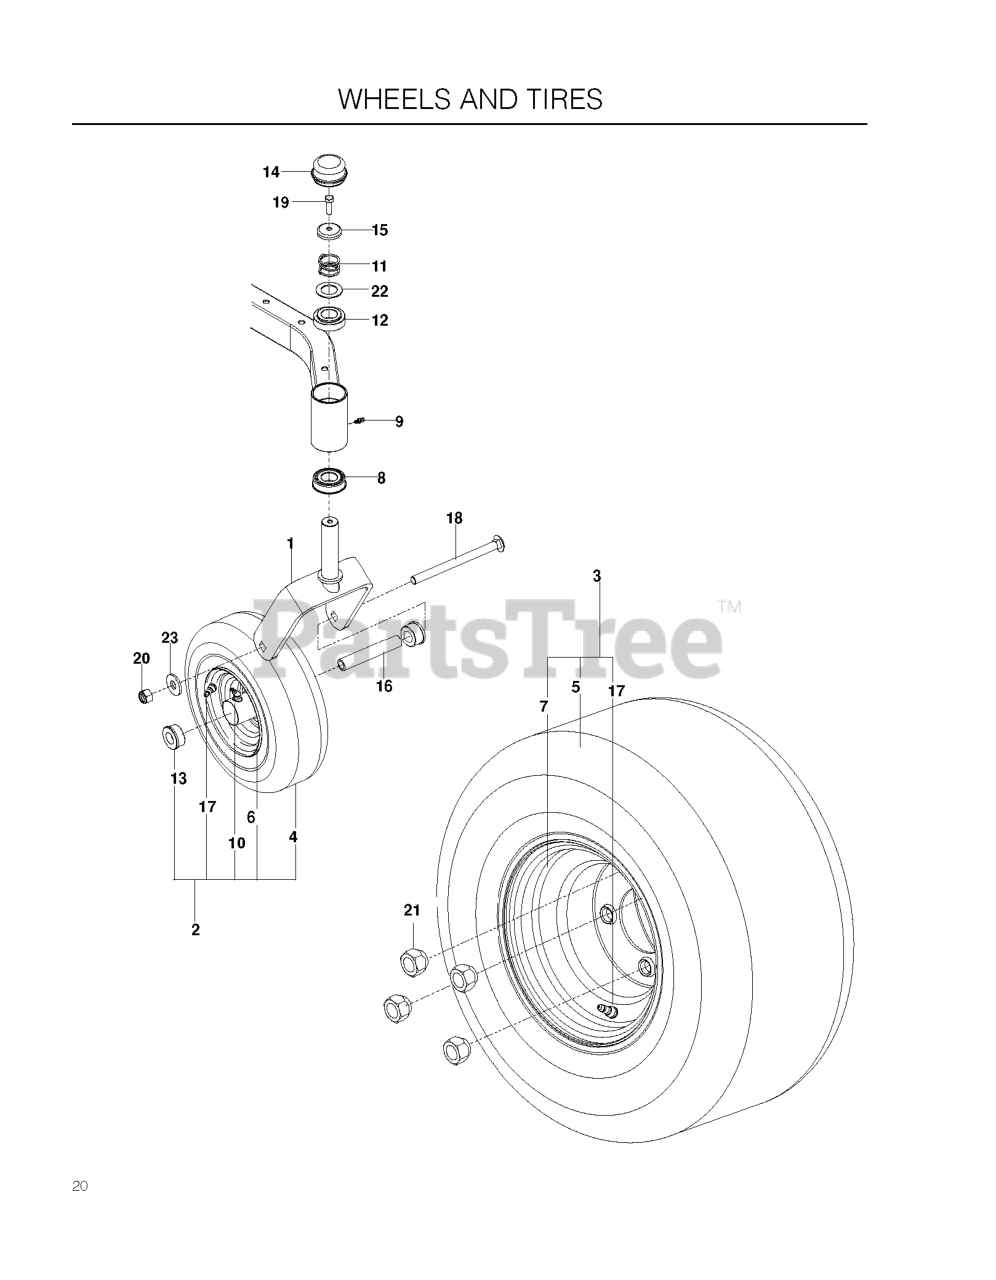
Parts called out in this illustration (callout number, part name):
1	YOKE.CASTER.ORANGE
2	WHEEL ASSY, WIDE, RZ
3	TIRE/WHEEL ASM 18X9.5-8
4	TIRE 11X6-5, 4 PLY
5	TIRE, 18 X 9.5 - 8
6	WHEEL 3.0 X 5.0
7	RIM.8X7.W/8".OFFSET.SILVER.ZTR
8	BEARING FLANGED
9	ZERK, 3/16, DRIVE IN
10	ZERK
11	SPRING, CASTER
12	BUSHING, CASTER
13	BUSHING
14	GREASE CAP
15	CASTER.PLUG
16	SPACER, PIVOT
17	VALVE STEM TR-412
18	RHSNB 1/2-13 X 7.5
19	5/16-18X1 HHB G5W/NY
20	NUT 1/2-13 HEX CNTRLK GR 5 ZD
21	LUG NUT 1/2F
22	WASHER, 1.025 ID X 1.64
23	WASH USS FLAT 1/2
